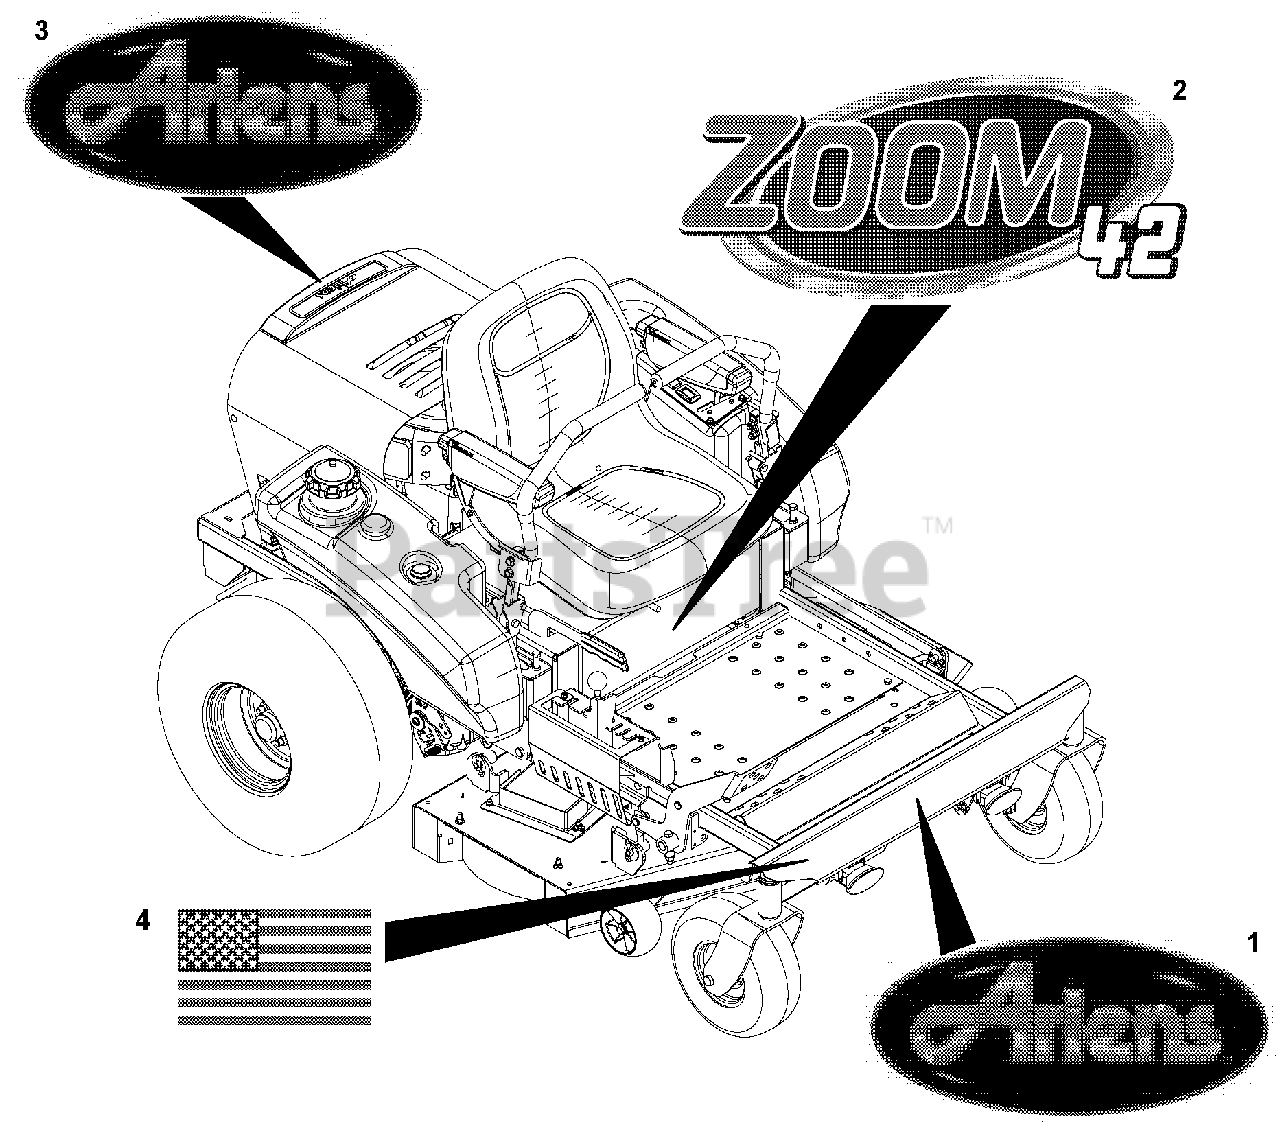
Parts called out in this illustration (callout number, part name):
1	DECAL, ARIENS JEWEL (LARGE)
2	DECAL,ZOOM 42 XL
3	DECAL, ARIENS JEWEL
4	DECAL, AMERICAN FLAG
